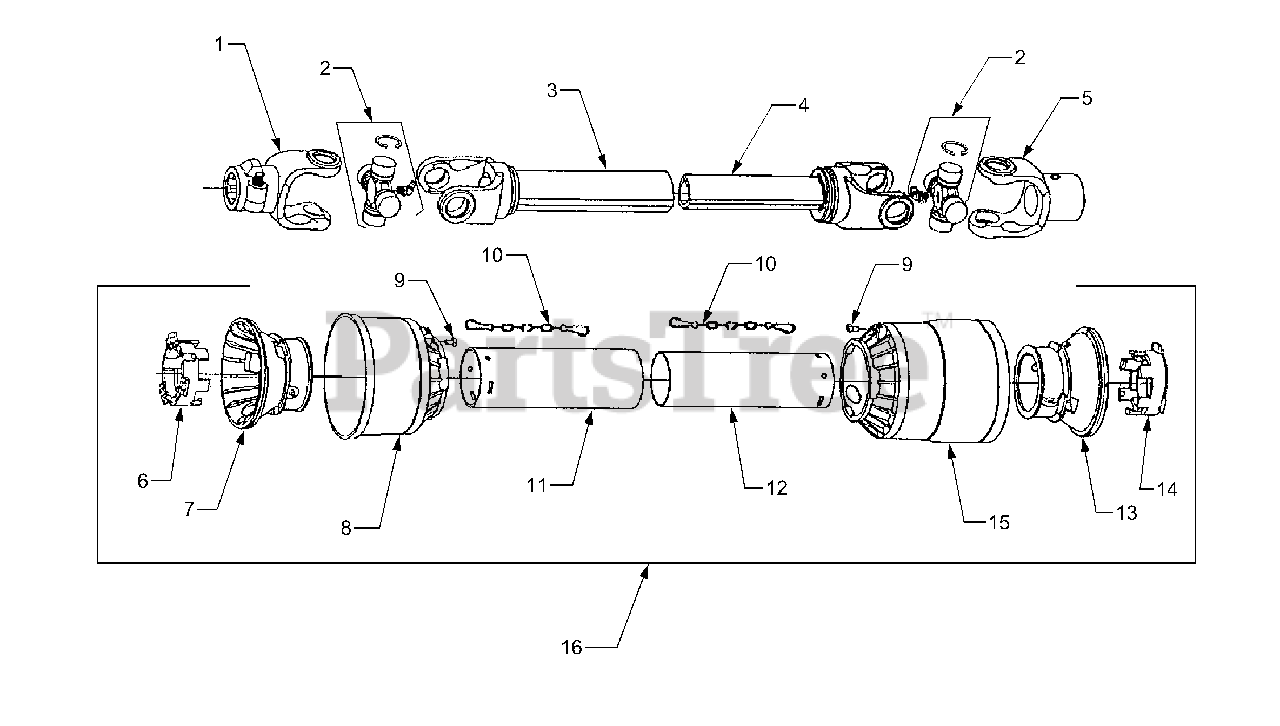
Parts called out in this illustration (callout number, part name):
1	Yoke Assembly (Tractor End)
2	Cross and Bearing
3	Outside Tube w/Yoke
4	Inside Tube w/Yoke
5	Yoke Assembly (Implement End)
7	Outer Tube Ridged Cone
11	Outer Tube Shield
12	Inner Tube Shield
13	Inner Tube Ridged Cone
15	Soft Collar
16	Complete PTO Shaft Shield
